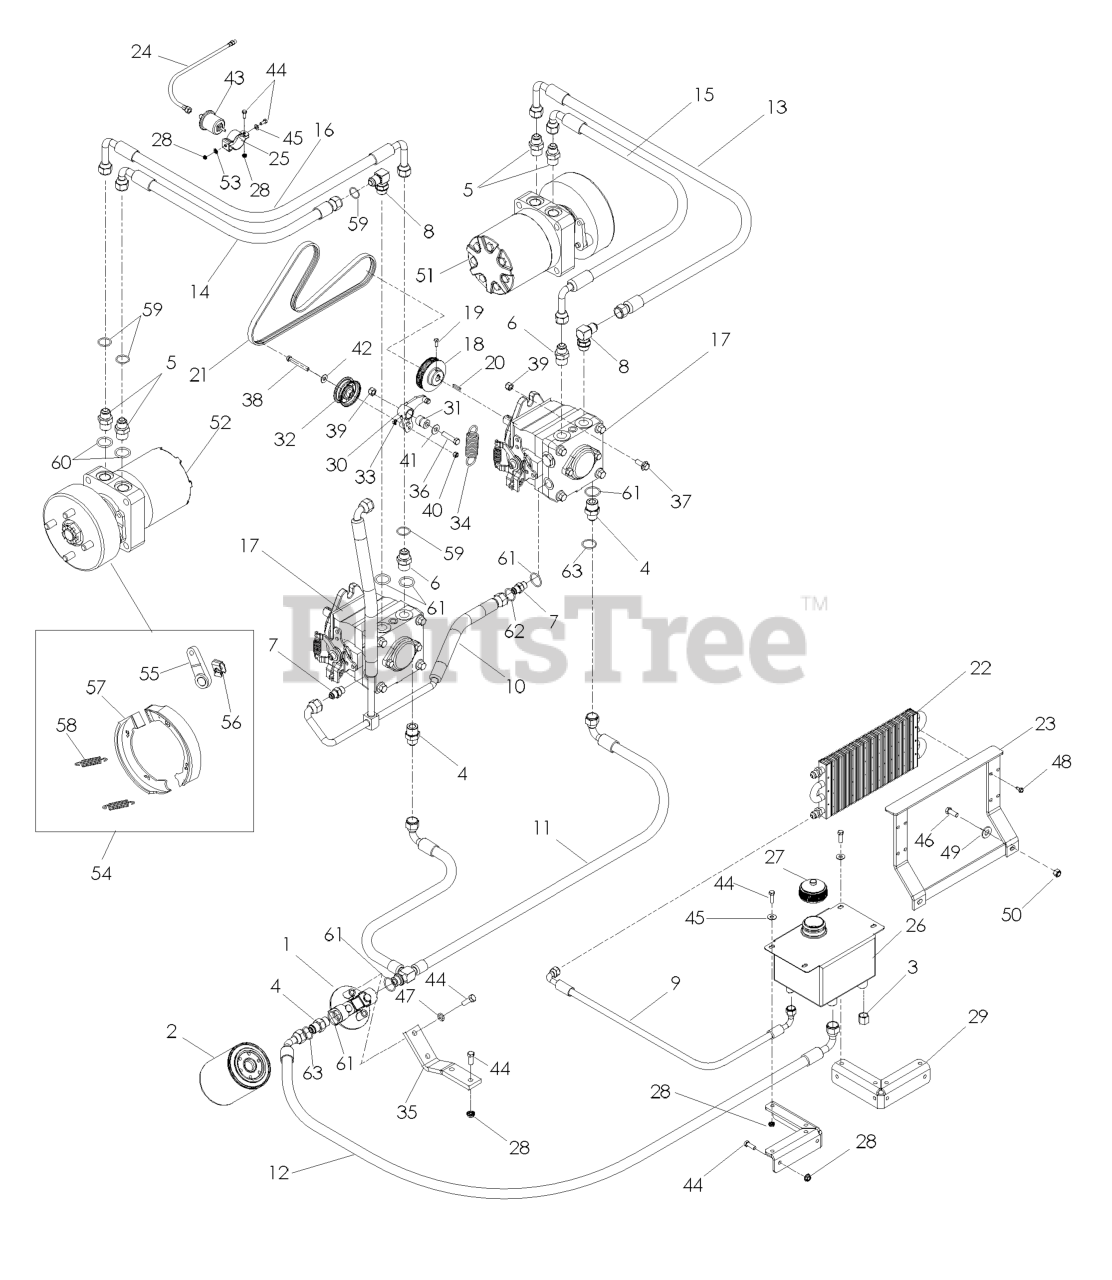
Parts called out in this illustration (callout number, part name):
1	FILTER HEAD
2	HYDRAULIC OIL FILTER
3	NUT 9/16-18 JIC CAP
4	FITTING, STRAIGHT F6400-8-8-0
18	PUMP SHEAVE
19	SCREW 5/16C X 1 SQ HEAD SET
20	KEY, METRIC
23	COOLER WLDMT MT
25	CLAMP-OIL SENDER
26	TANK, OIL = PAINTED
27	HYDRAULIC CAP
28	NUT 1/4-20 HEX FLG LK ZD
30	ARM WELDMENT
32	IDLER PULLEY
35	FILTER MOUNT - PAINTED
36	HEX SCREW 1/2-13 X 2.5" GR 5
37	HCS 1/2C X 1 1/4 SERRATED HEAD
38	HCS 3/8C X 3
39	NUT 1/2-13 HEX NYLOC ZD
40	NUT 3/8-16 NYLOC
41	WASHER 1/2 FLAT
42	WASHER 3/8 SAE FLAT
43	SENDER,OIL PRESS
44	HCS 1/4C X 3/4 HCS
45	WASHER 1/4 FLAT
46	HCS 5/16C X 1
47	LOCKWASHER 1/4"
48	SCR #10-12X3/4 HEX WAS HD ZD
49	WASHER 5/16 FLAT
50	NUT 5/16 NYLOC
51	WHEEL MTR ASM
52	WHEEL MTR ASM, RT
53	WASHER 1/4 EXTLW STAR ZD
54	SHOE ASM.
58	RETURN SPRING
